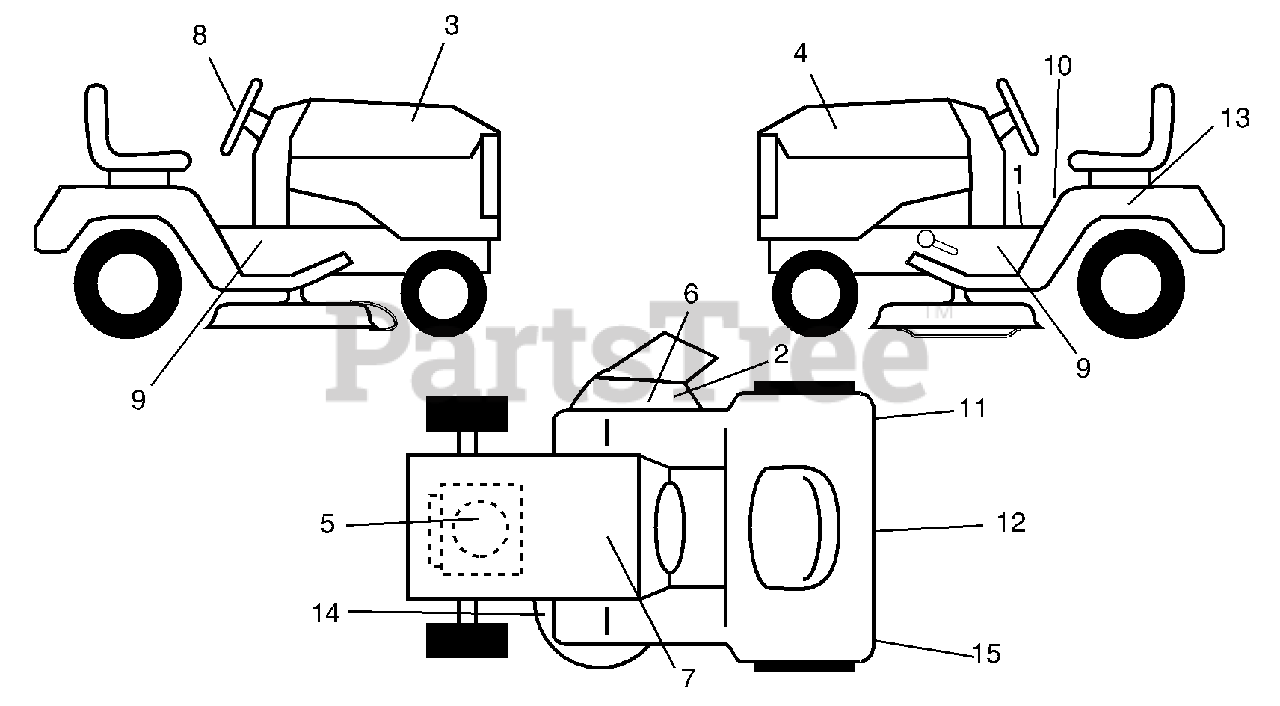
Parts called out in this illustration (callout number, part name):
1	Decal Oper
2	Decal Deck Warn.
3	Decal Hood RH Agway
4	Decal Hood LH Agway
5	Decal HP Engine
6	Decal Deck "B" 42"
7	Decal Repl. Parts
8	Decal Steering Wheel Agway
9	Decal 18/42 Agway
10	Decal Fender Danger E/F
11	Decal RH FNDR Reflector
12	Decal Agway
13	Decal Battery
14	Decal V-Belt Schematic
15	LH FNDR Reflector
